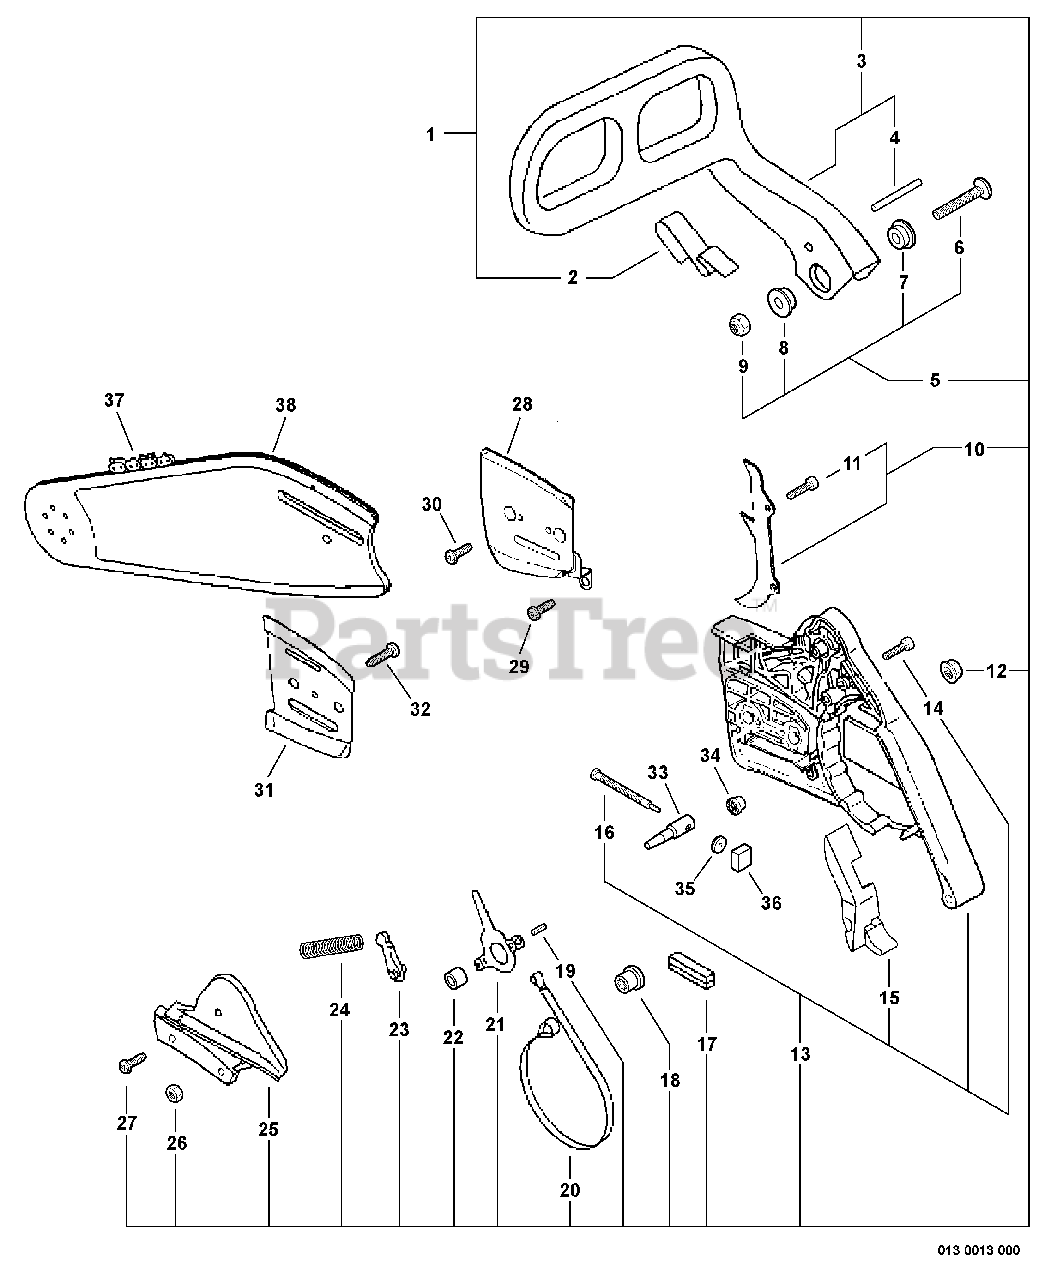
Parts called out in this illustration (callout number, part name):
1	CHAIN BRAKE ASSY
2	SPRING, RETURN
3	LEVER, BRAKE
4	PIN - 3.5X26
5	MOUNTING KIT
6	SCREW - 5X35
7	COLLAR - 5
10	SPIKE KIT
11	SCREW - 5X12
12	NUT - FLANGE
13	SPROCKET GUARD KIT
14	SCREW - 3X18
15	CUSHION
16	SCREW, TENSIONER
18	ADJUSTER, BRAKE BAND
19	PIN - SPRING -- 4X8
20	BAND, BRAKE
21	LEVER, BRAKE
22	SPACER - 8
23	STOPPER, BRAKE
24	SPRING, BRAKE
25	COVER, BRAKE
27	SCREW - 4X12
28	PLATE, GUIDE - OUTER
29	SCREW - 4X10
30	SCREW - 3X6
31	PLATE, GUIDE - INNER
32	SCREW - 4X8
33	TENSIONER, CHAIN
34	GEAR - PINION
35	GEAR - BEVEL
36	COLLAR - 8
37	CHAIN -- CARBICHAIN QUICKVENT
38	GUIDE BAR - QUICKVENT
